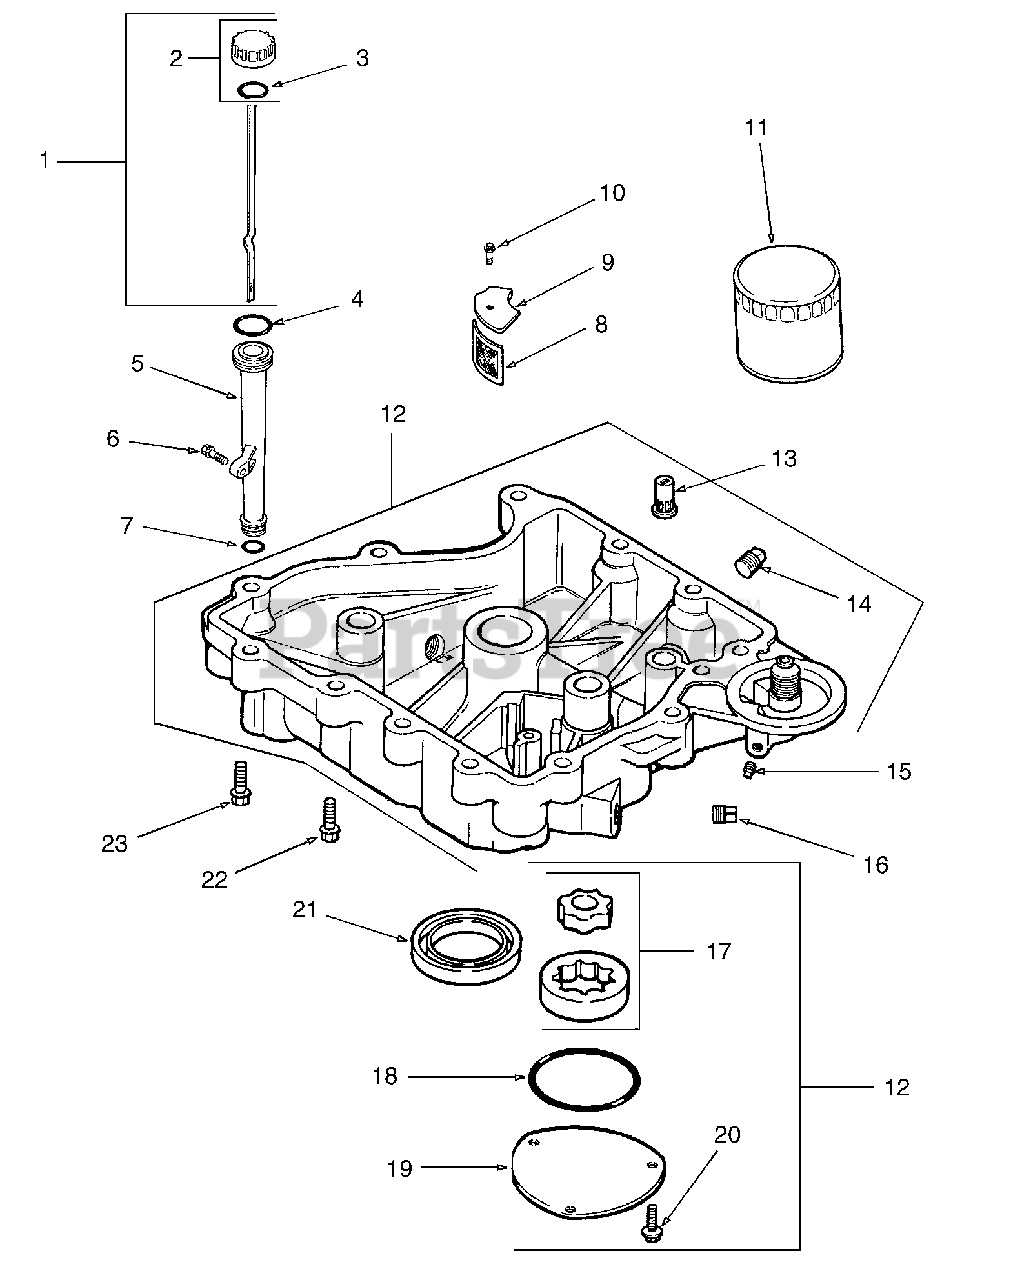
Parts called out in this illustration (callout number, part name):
1	Dipstick Ass'y
2	Cap Kit, Oil Fill
3	O-Ring, Dipstick
4	O-Ring,Upper Oil Fill Tube
5	Tube, Oil Fill
6	Screw, Hex Flange, M5 x 0.8 x 20
7	O-Ring, Lower Oil Fill Tube
9	Cover, Oil Pick-up Screen
10	Screw, Hex Flange, M5 x 0.8 x 16
11	Filter, Oil
12	Pan Ass'y, Oil
13	Valve, Oil Pressure
14	Plug, Pipe
15	Plug, Square Hd 1/8
16	Plug, Square Hd 3/8
17	Pump Ass'y, Oil
18	O-Ring, Oil Pump Cover
19	Cover, Oil Pump
20	Screw, Hex Flange, M5 x 0.8 x 16
21	Seal, Oil (PTO End)
22	Screw, Hex Flange, M8 x 1.25 x 45
23	Screw, Hex Flange, M8 x 1.25 x 45
